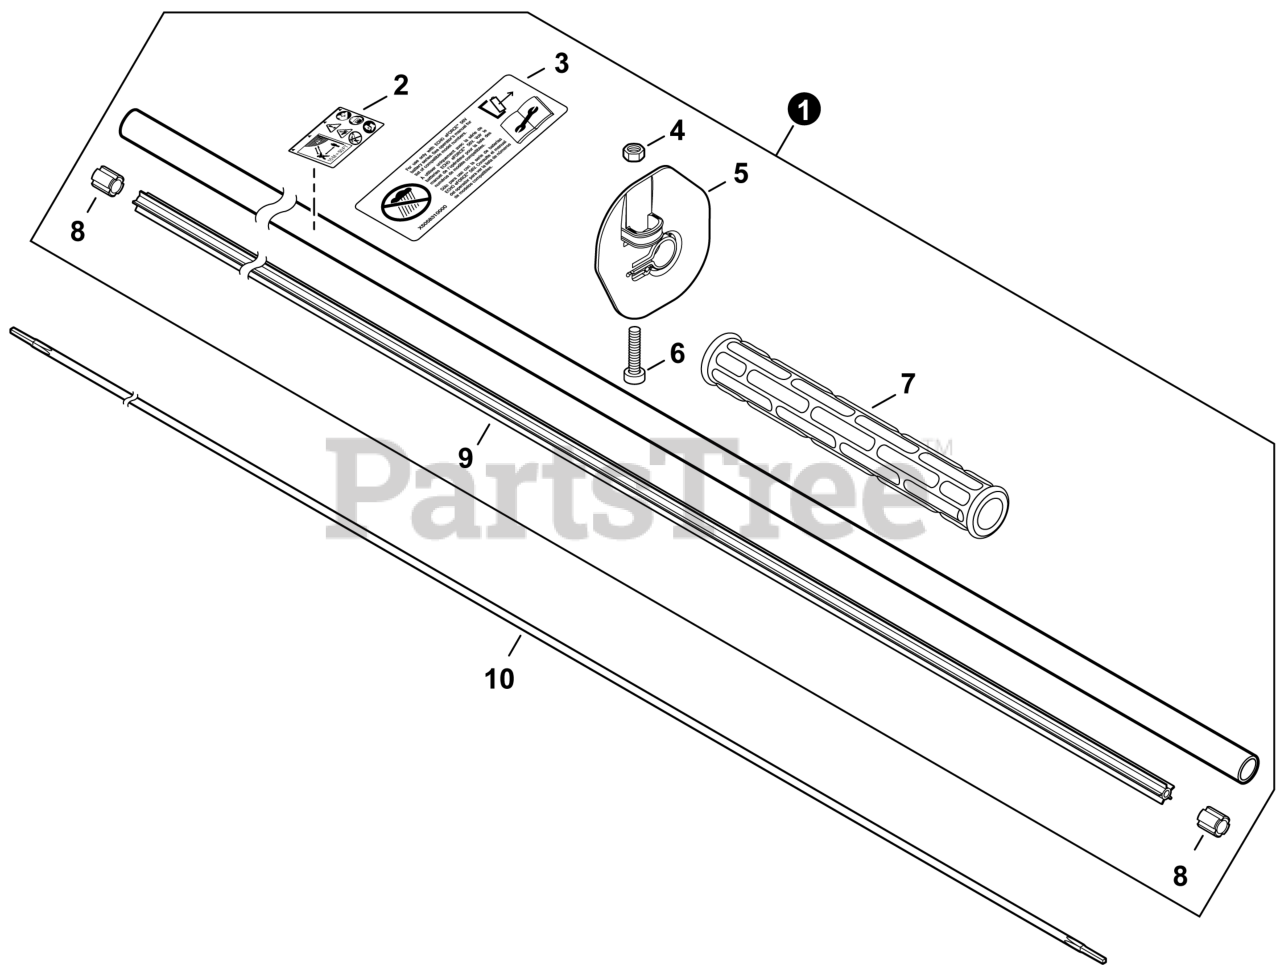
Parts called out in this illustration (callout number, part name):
1	MAIN PIPE ASSY
2	LABEL - CAUTION ISO
3	LABEL - CAUTION - UL
5	GUARD, HAND
6	BOLT, TORX 5x20
7	GRIP, FRONT
9	LINER, FLEXIBLE 21.6x1420
10	DRIVESHAFT - FLEXIBLE
